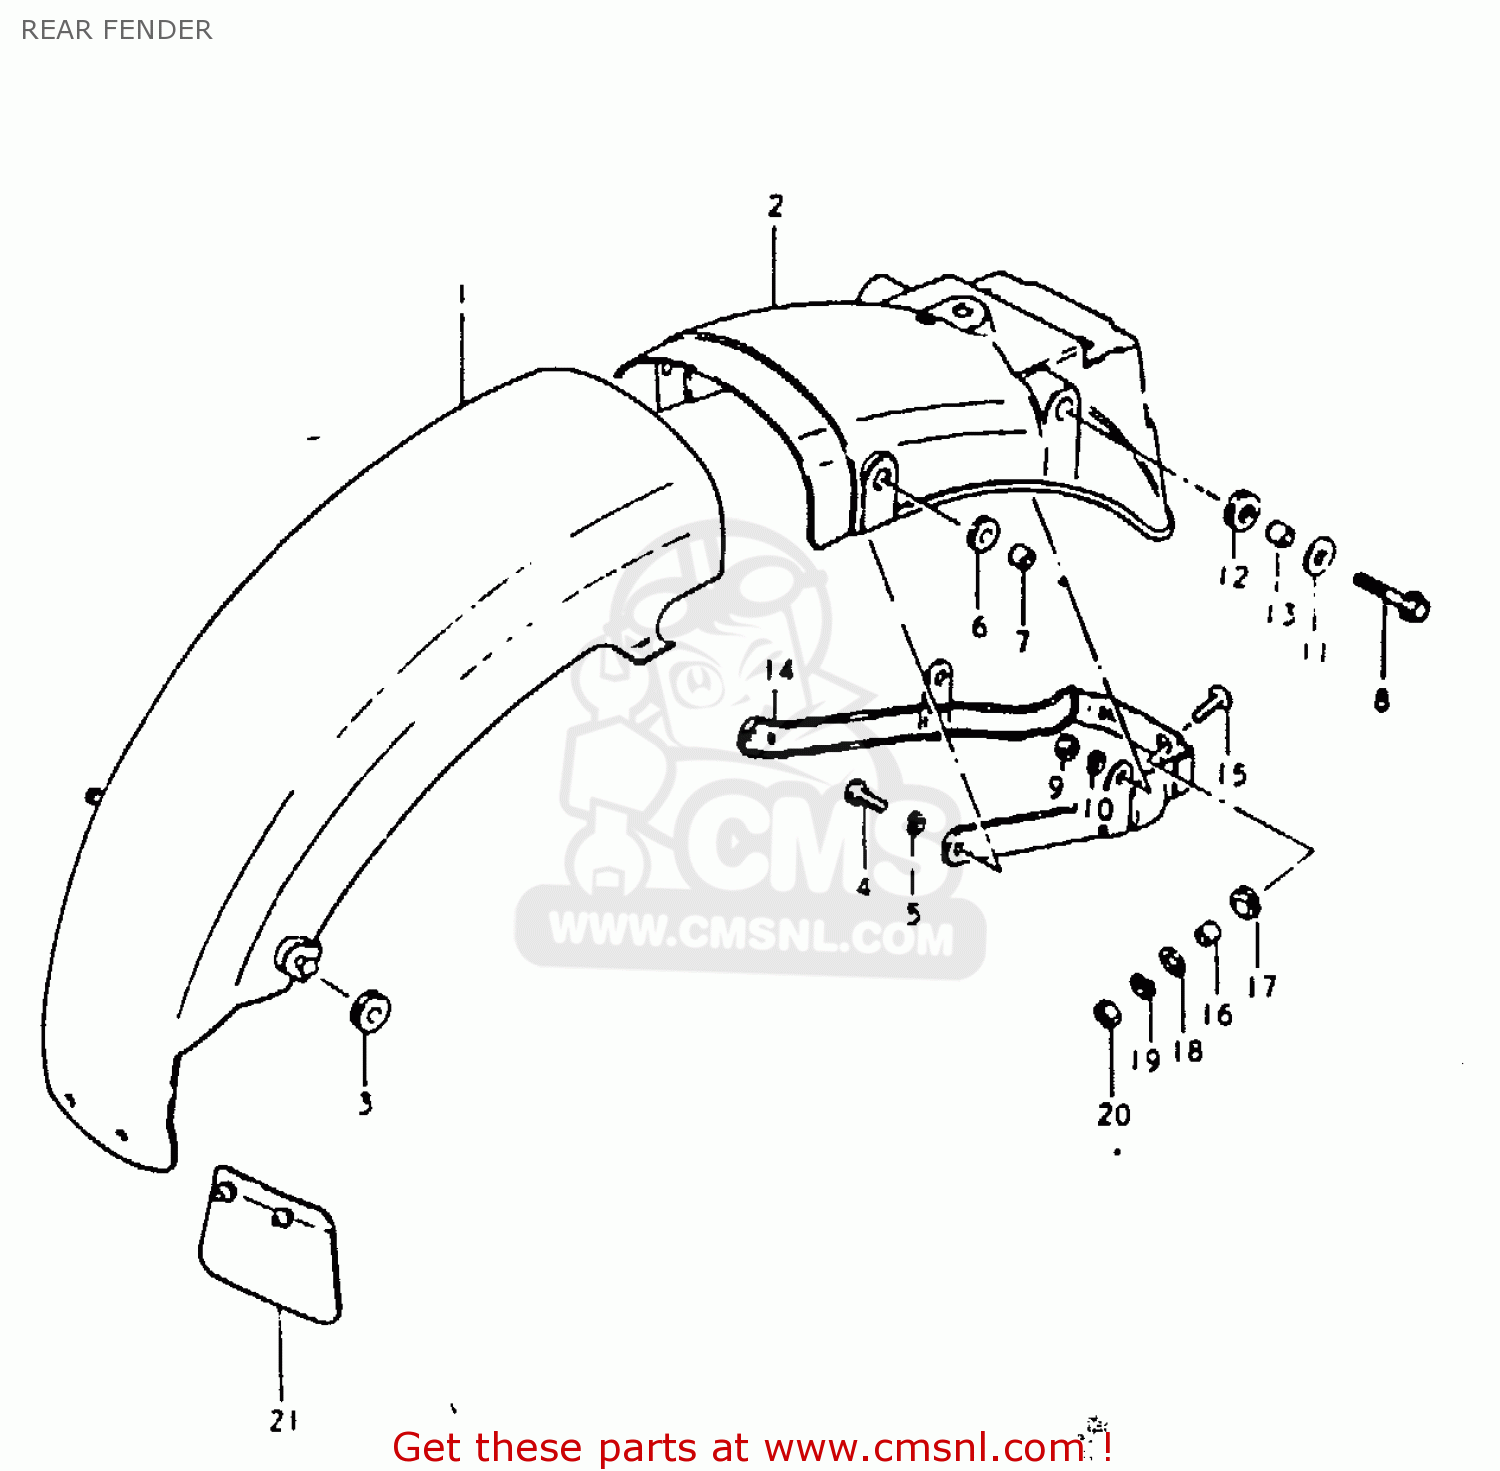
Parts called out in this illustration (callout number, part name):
1	FENDER,REAR
2	BODY,RR FENDER RR
3	CUSHION
4	BOLT
5	LOCK WASHER
6	CUSHION
7	SPACER(6.1X9X7.5)
8	BOLT
9	NUT
10	LOCK WASHER
11	WASHER(8.5X26X1.2)
12	CUSHION
13	SPACER (8.2X12X7.5)
14	REINFORCEMENT,REAR FENDER
15	SCREW
16	SPACER (6.1X9X9)
17	CUSHION
18	WASHER(6,5X22X1.6)
19	LOCK WASHER
20	NUT
21	GUIDE,RR FENDER MUD
